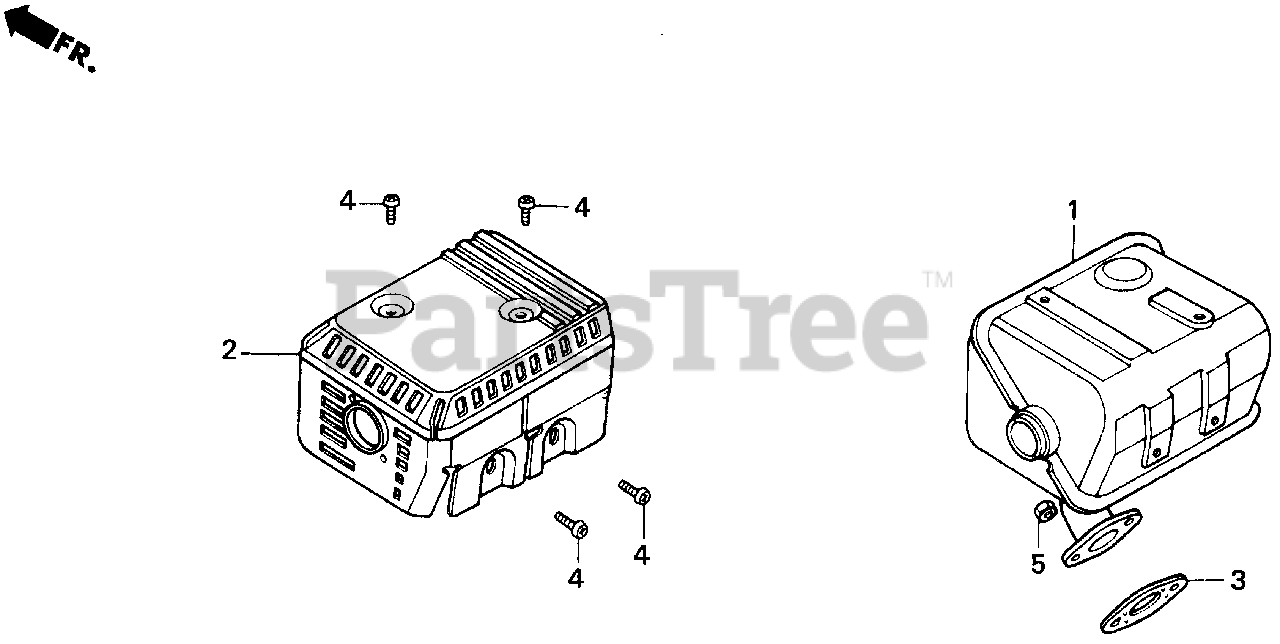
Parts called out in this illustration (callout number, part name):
1	MUFFLER (STD)
2	PROTECTOR, MUFFLER (STD) (BLACK)
3	GASKET, MUFFLER
4	SCREW, TAPPING (5X8)
5	NUT, HEX. (8MM)
